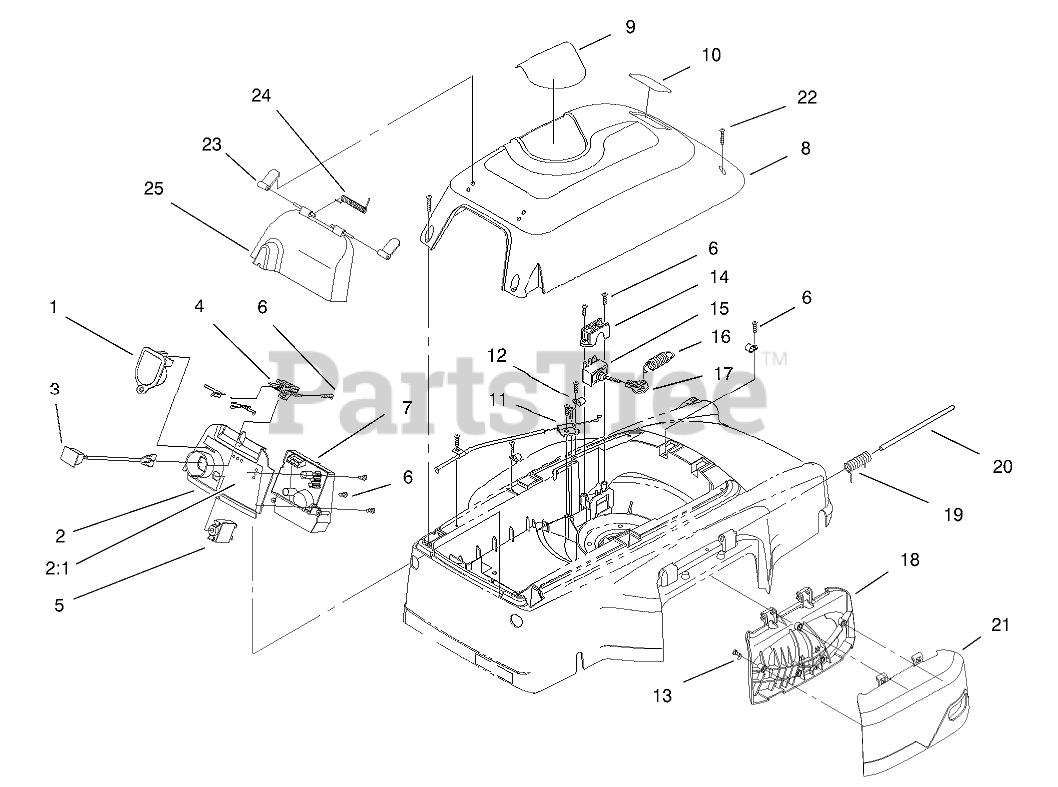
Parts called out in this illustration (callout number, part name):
2	PANEL ASM
2:1	DECAL - CONTROL PANEL
3	PLUG ASM
4	HOUSING - PLUG
5	CIRCUIT BREAKER
6	SCREW-PPH
7	Charger
8	COVER ASM
9	DECAL - COVER
10	PLATE-LOGO
11	BRACKET - CABLE
12	CLIP - WIRE
13	SCREW
14	CLAMP - SWITCH, TOGGLE
15	SWITCH - TOGGLE
16	SPRING - SWITCH
17	COVER LEVER-SWITCH
18	OBS MULCH PLUG - INSIDE
19	SPRING - TORSION
20	PIN - HINGE, MULCH PLUG
21	PLUG - OUTSIDE MULCH
22	SCREW-PPH
23	TAB - SHIELD
24	SPRING - TORSION, SHIELD
25	SHIELD - RAIN
